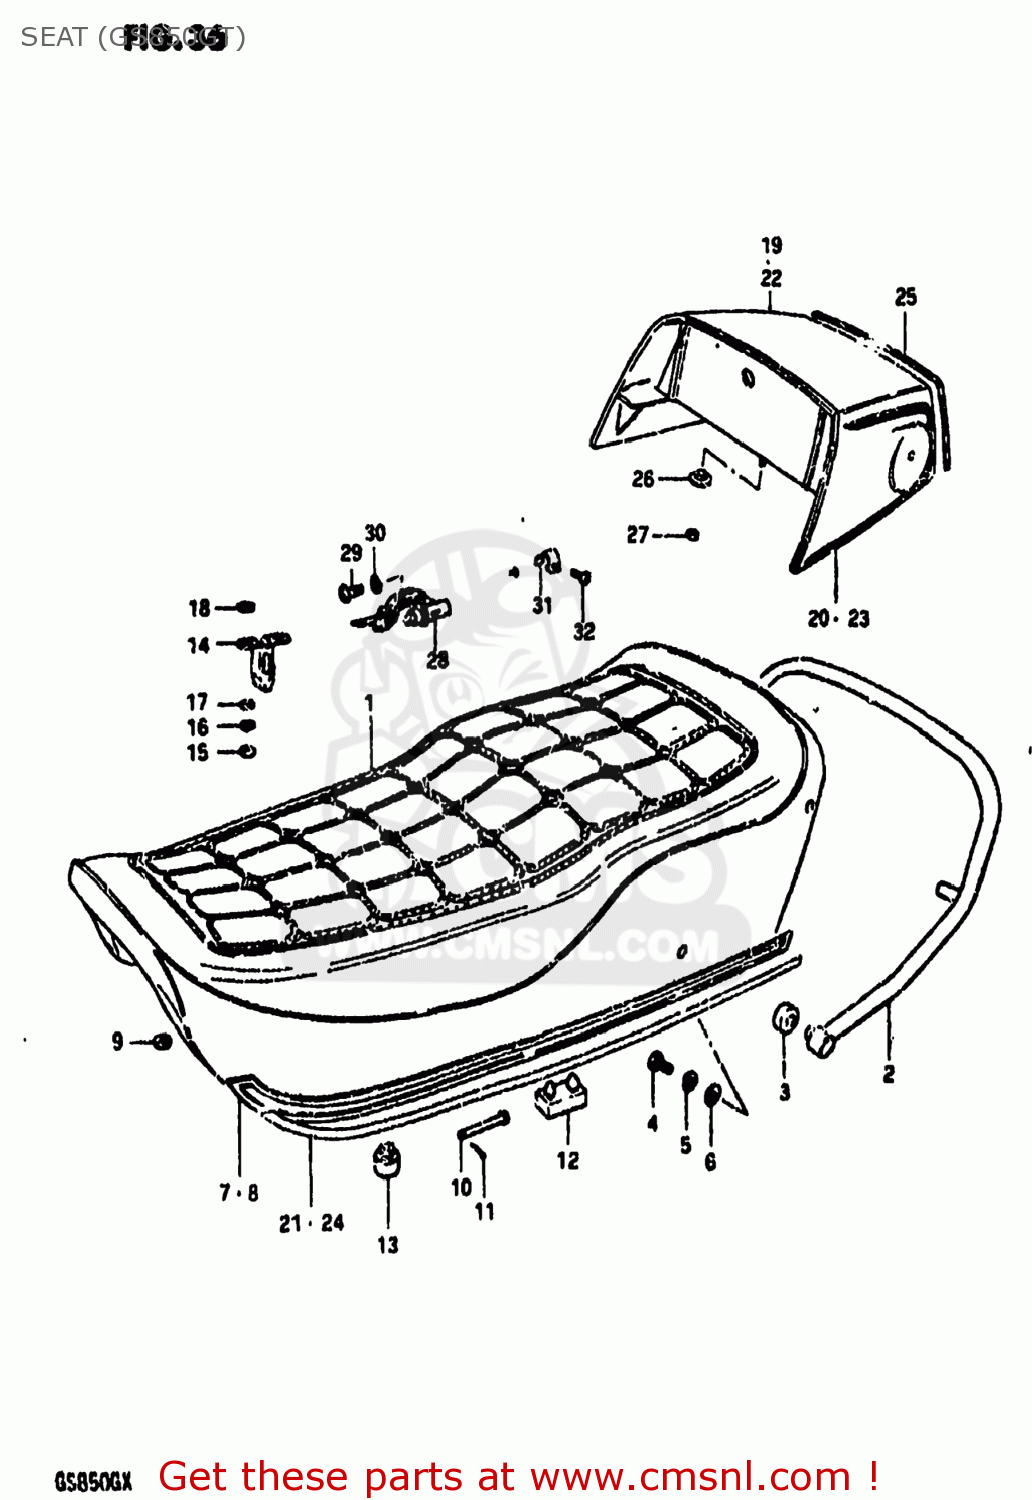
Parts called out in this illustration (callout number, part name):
1	SEAT ASSEMBLY
2	HANDLE,PILLION RIDER
3	CUSHION
4	BOLT
5	LOCK WASHER
6	WASHER
7	MOLE,R
8	MOLE,L
9	NUT
10	PIN
11	PIN
12	CUSHION
13	CUSHION
14	STRIKER,SEAT LOCK
15	NUT
16	LOCK WASHER
17	WASHER
18	WASHER (6.5X20X1.2)
19	BOX SET,SEAT TAIL
20	TAPE SET,SEAT TAIL COVER
21	TAPE SET
22	BOX SET,SEAT TAIL
23	TAPE SET,SEAT TAIL COVER
24	TAPE SET
25	MOLDING,SEAT TAIL COVER
26	WASHER
27	NUT 6MM
28	LOCK ASSY,SEAT
29	SCREW
30	LOCK WASHER
31	SPRING,HELMET HOLDER
32	SCREW
